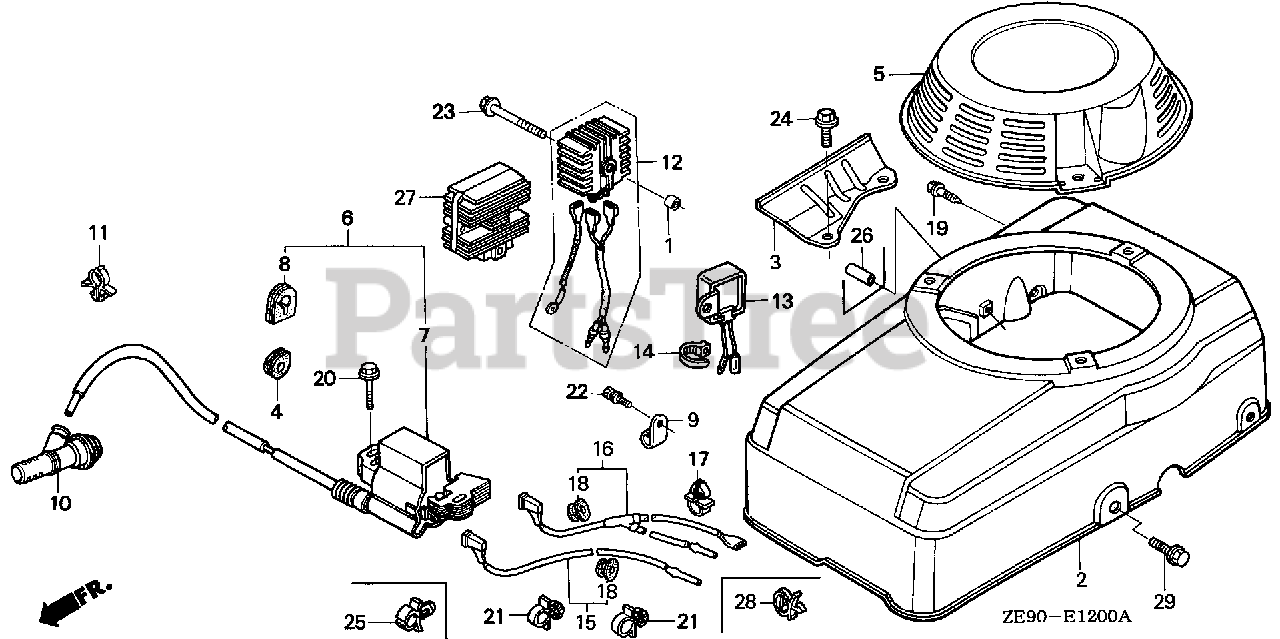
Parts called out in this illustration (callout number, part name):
2	COVER, FAN
6	COIL ASSY., IGNITION (NOT AVAILABLE)
8	GROMMET, IGNITION
9	CLAMP, IGNITION WIRE
10	CAP ASSY., NOISE SUPPRESSOR
15	WIRE, STOP SWITCH
16	WIRE, STOP SWITCH
17	HOLDER, STOP SWITCH WIRE
18	GROMMET, WIRE CORD
19	BOLT, FLANGE (6X12) (CT200)
20	BOLT, FLANGE (6X28) (CT200)
22	SCREW-WASHER (5X12)
